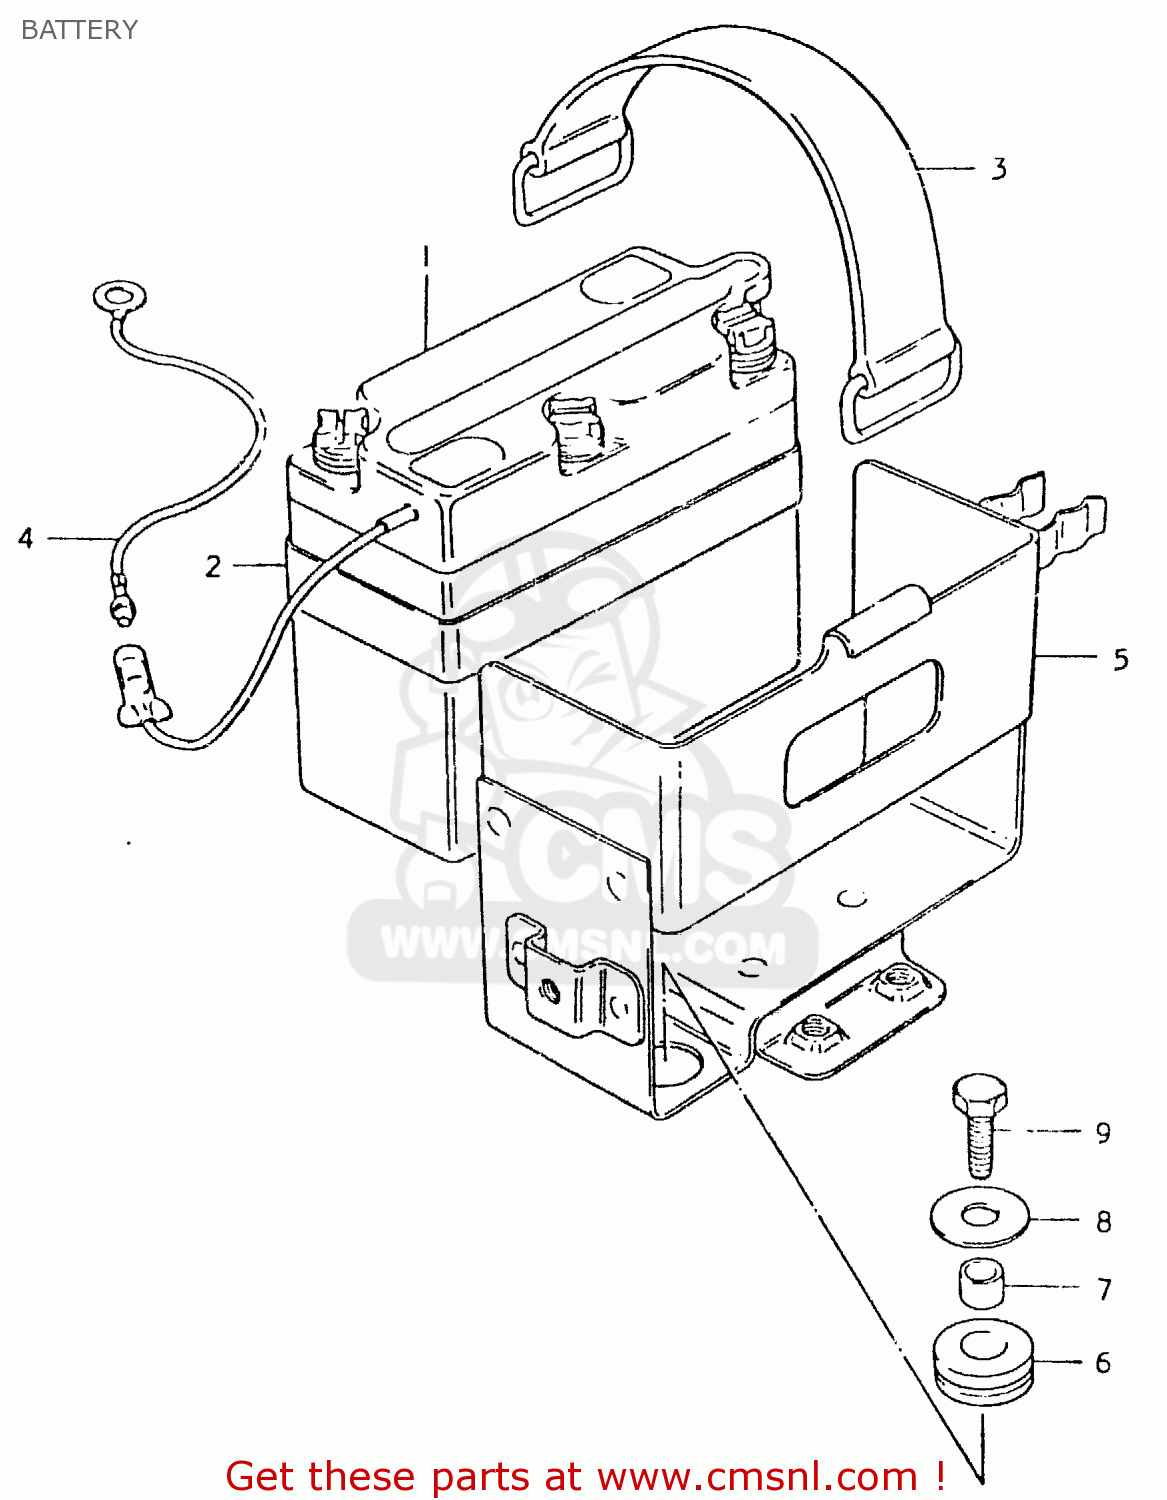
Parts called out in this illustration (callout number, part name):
1	BATTERY(6N4B-2A,6V4.2AH)
2	PROTECTOR,BATTERY
3	BAND
4	LEAD WIRE
5	HOLDER,BATTERY
6	CUSHION
7	SPACER (7X9X7)
8	WASHER (6.5X20X1.2)
9	BOLT, UPPER
